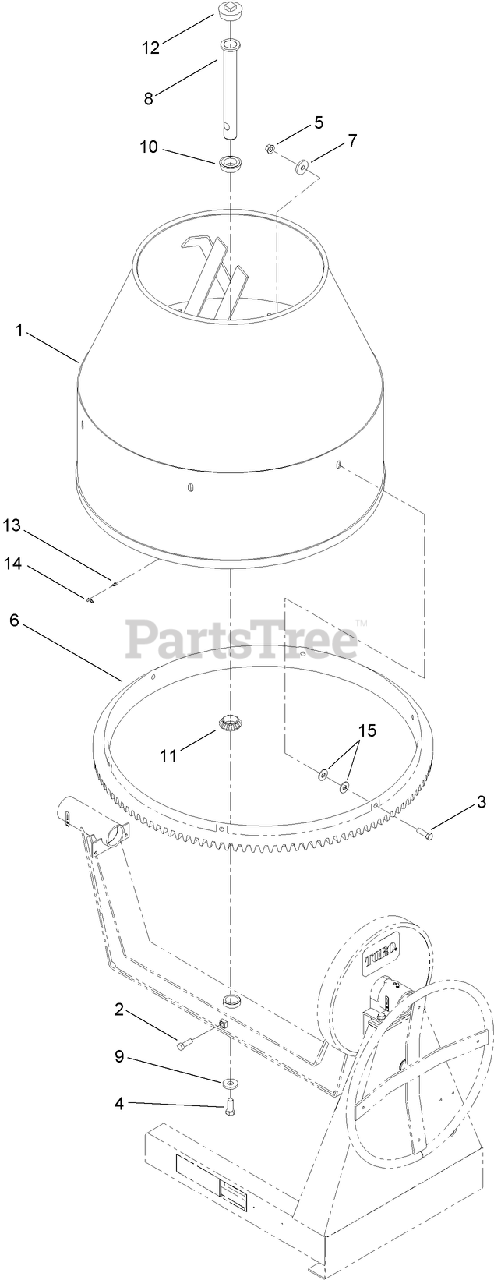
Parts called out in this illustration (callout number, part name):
2	SCREW-HH
3	SCREW-HH
4	SCREW-HH
5	NUT-LOCK
6	GEAR-RING
7	WASHER-FLAT
8	SPINDLE
9	WASHER-FLAT
10	BEARING
11	BEARING-ROLLER
13	FITTING
14	CAP-PLUG
15	WASHER-FLAT
